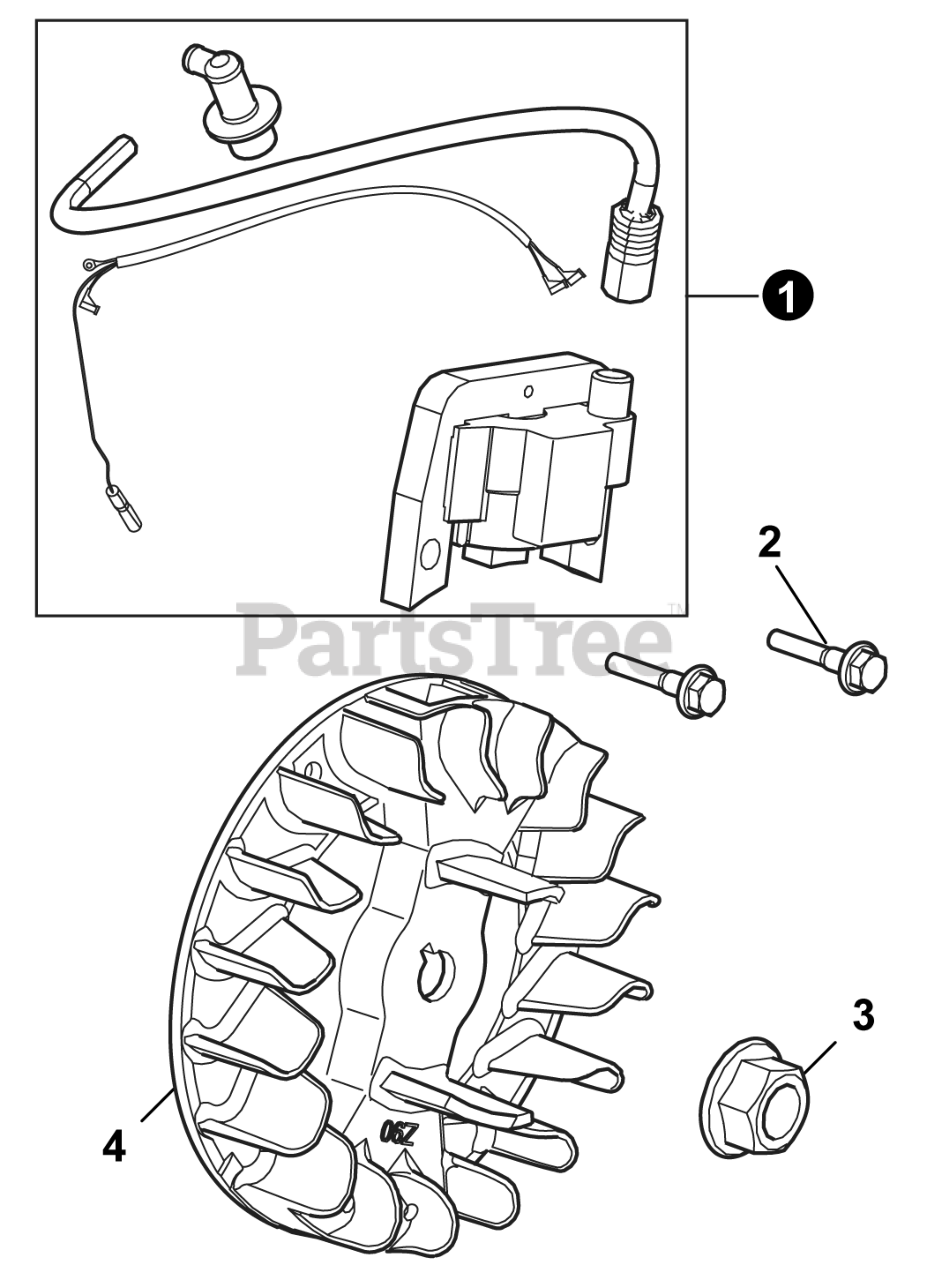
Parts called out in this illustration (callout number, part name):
1	COIL, IGNITION
3	NUT, FLYWHEEL
4	FLYWHEEL ASSY.
